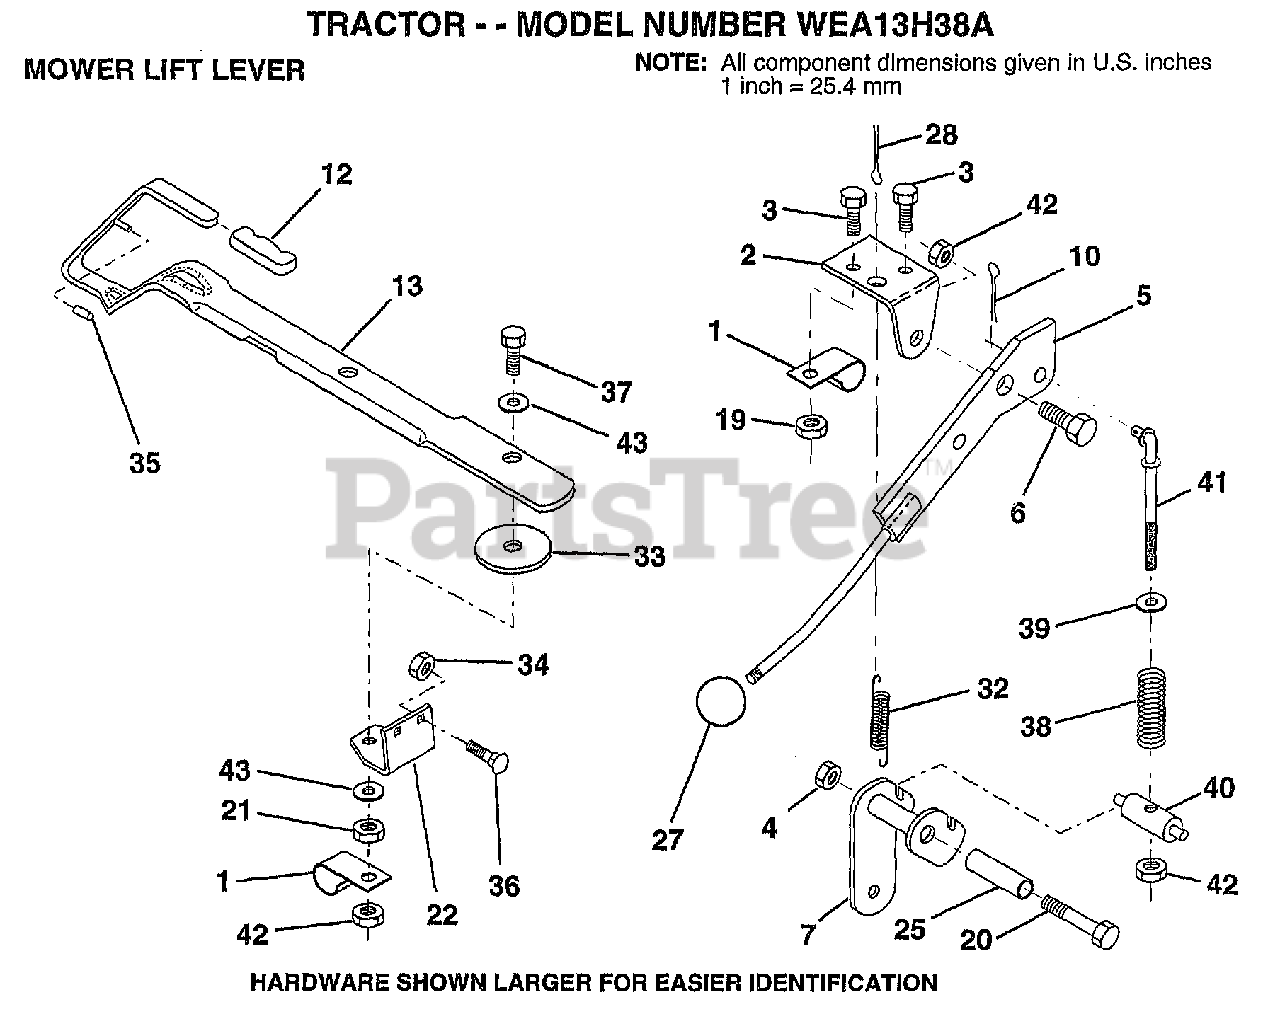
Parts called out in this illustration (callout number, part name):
1	"CLIP,INSULATOR"
2	BRKT CLUTCH
3	BOLT HXHD FIN
5	LEVER.ASM.CLUTCH
6	"BOLT, SHOULDER LT"
7	ARM.CLUTCH.ASM
10	COTTER PIN
12	GRIP HANDLE
13	LEVER LIFT LR
20	BOLT
21	LOCKNUT
22	LIFT LEVER BRKT
25	TUBE SPACER
27	KNOB T(3/8 HOLE)
28	COTTER PIN
32	SPRING EXT
33	WASHER
34	NUT
35	VINYL CAP RED
36	BOLT
37	BOLT
38	COMP CLUTCH SPRNG
39	WASHER HYT
40	TRUNNION
41	ROD TENSION CLUTC
42	NUT
43	WASHER
